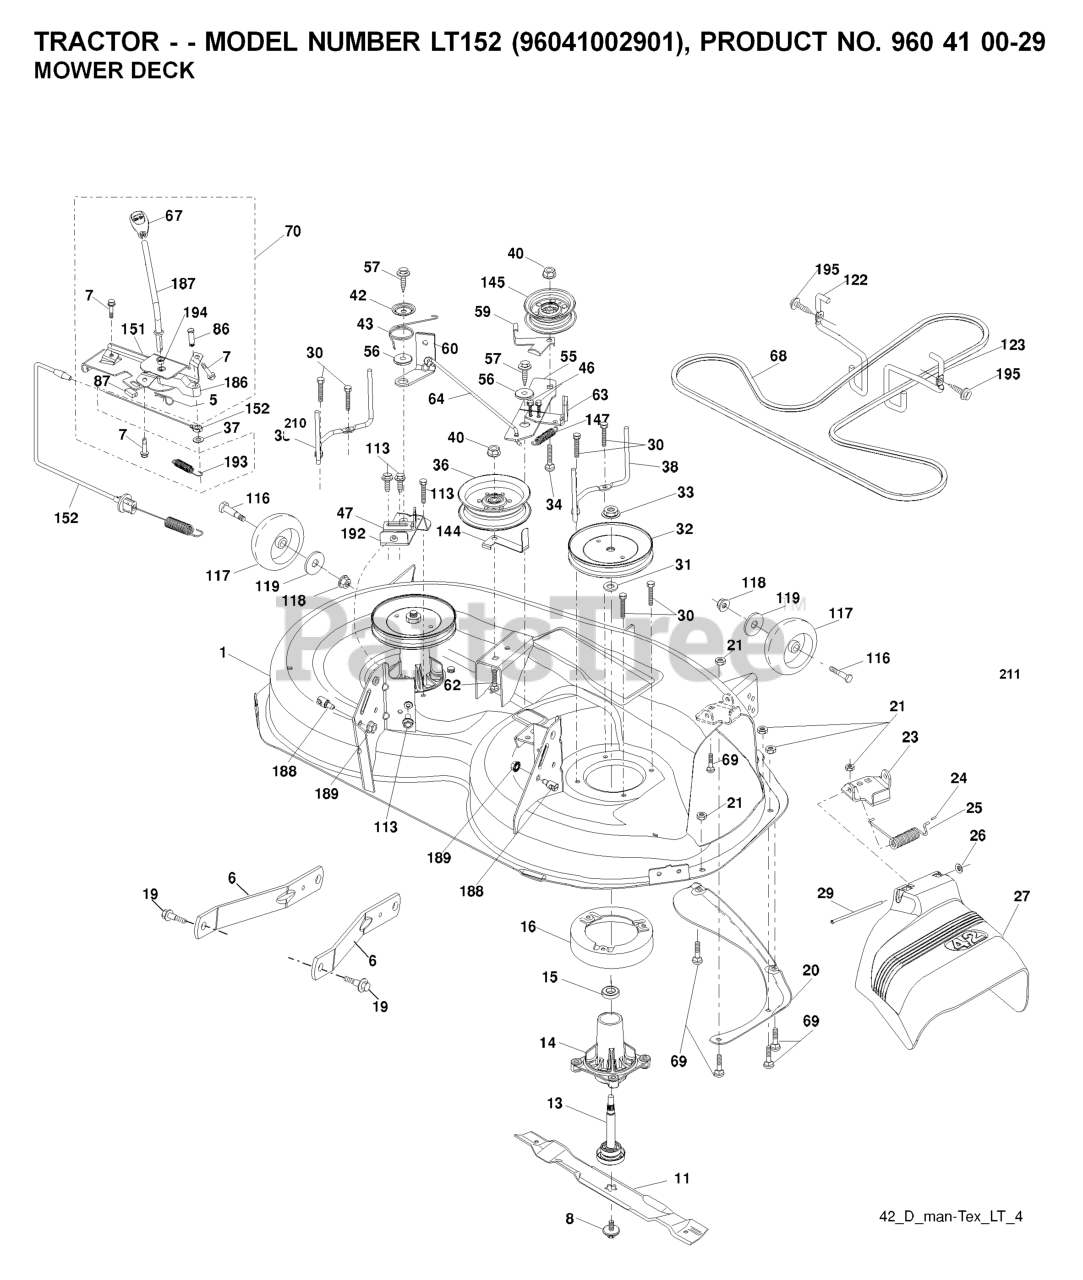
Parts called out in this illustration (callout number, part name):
1	DECK.WELDMENT.42"
5	RETAINER-SPRNG RB
6	ARM.SUSPENSION.MOWER.R
7	SCREW
8	BOLT.WASHER.ASM.7/16-2
11	42" HI-LIFT BLADE
13	SHAFT.ASM.MDRL.N/GREASE.38
14	RP.HOUSING.MANDREL.4PT.
16	STRIPPER.MANDREL.ROUND.BLACK
19	BOLT.SHOULDER
20	BAFFLE.VORTEX
21	LOCKNUT
23	BRKT.DEFLECTOR.38"2005+
24	CAP-SLEEVE LT
25	SPRING.TORSION.DEFLECT
26	NUT PUSH M
27	SHIELD.DEFLECTOR.MOWER.42"BLAC
29	ROD.HINGE
30	SCREW, WASHER HEAD
31	WASHER.SPACER.MANDREL
32	PULLEY.MANDREL.5.438.PD
33	NUT.FLANGE.LOCK.TOP
34	BOLT.3/8-16X1.50
36	PULLEY.IDLER.2006
37	WASHER
38	KEEPER.BELT.LH.MANDREL
40	NUT LOCK FLG 3/8-16 UNC
42	SPRING.TORSION.BRAKE
43	SRPING.TORSION.RETAINE
46	SCREW.1/4-20X5/8
47	BRKT.CLUTCH.CABLE
56	SPACER.RETAINER
57	SCREW 3/8-16X1
59	GUARD, BELT
60	ARM BRAKE MOWER
63	ARM BRAKE MOWER
64	LINK BRAKE
67	HANDLE.CLUTCH.CABLE.LT
68	BELT.DRIVE.MOWER.TEX.42"
69	BOLT
70	CLUTCH.ASM.MANUAL.LT.PRED
86	PIN ATTACHMENT CABLE
87	SWITCH.INTRLCK.CLUTCH.
113	BOLT.5/16HEX.WHS.HD
115	BOLT.CARR.5/16-18X5/8.SHORT
116	BOLT M
117	WHEEL.GAGE.HALF.SPOKED
118	LOCKNUT
119	WASHER.5/16.FLAT.STE.STD.
122	KEEPER BELT ENGINE LH
123	KEEPER BELT RH
144	KEEPER.BELT.MOWER
145	PULLEY.IDLER.48"PRIMARY
147	RETURN SPRING
151	BRACKET.CLUTCH CBL.PRED LT
152	CLUTCH CABLE
186	ARM ACTUATOR
187	LEVER.CONTROL.CL.CABLE.PRED LT
188	STUD.FASTNER.W/ANTI-ROTATE
189	NUT LOCK HEX FLANGE 5/16-18
192	BRKT.BRAKE.STAND.LH.
193	SPRING.PLUNGER.ACTUATOR
194	BEARING.CONTROL.LEVER.CLUTCH
195	SCREW, 3/8-16X3/4
